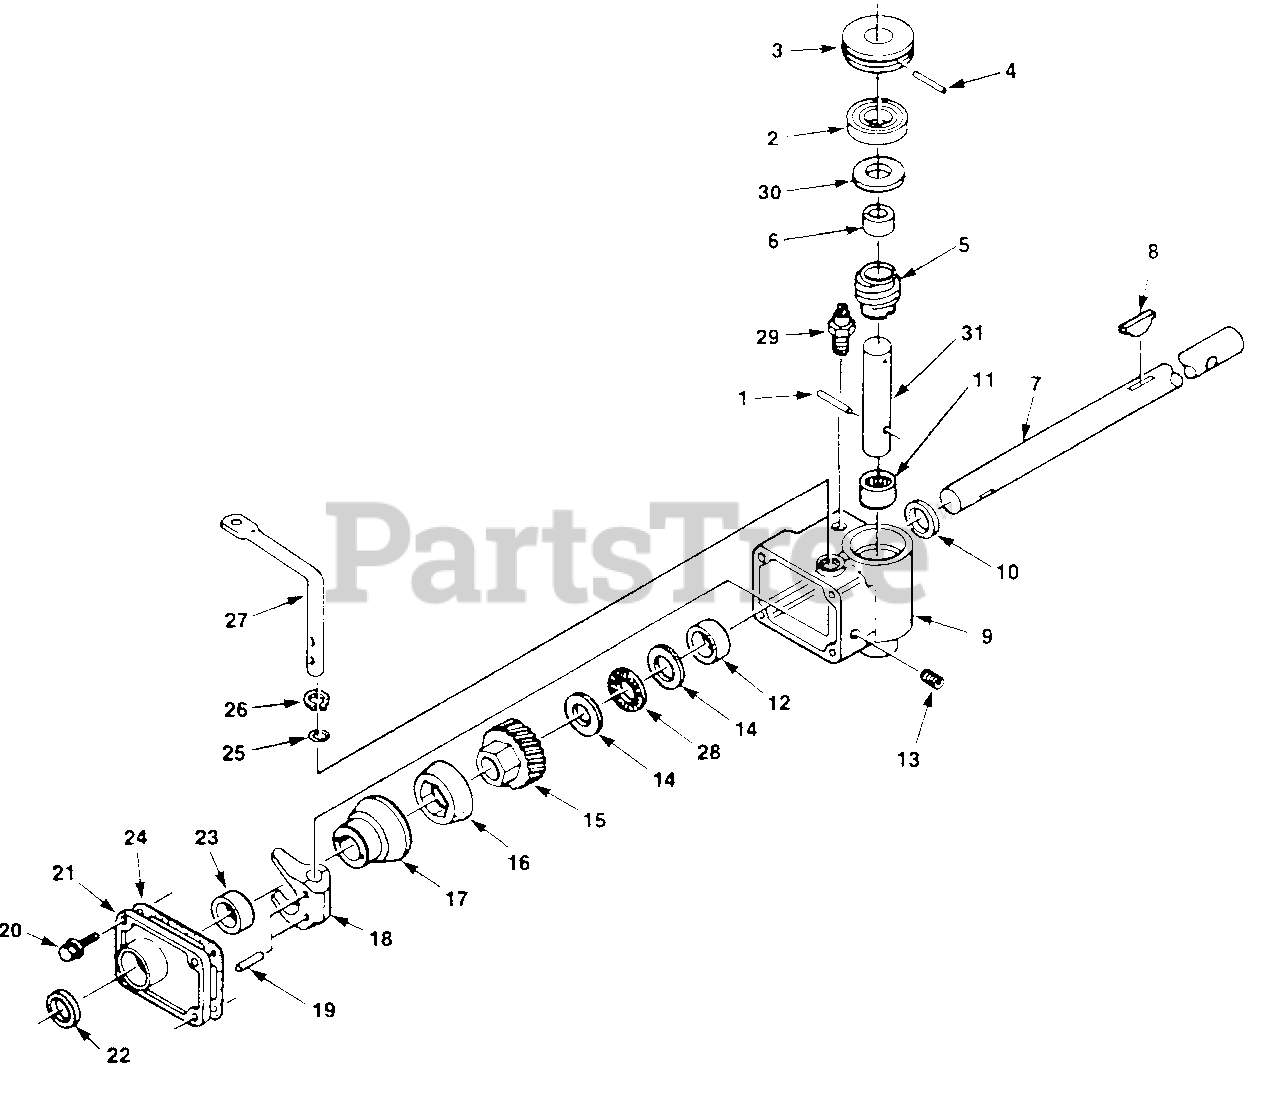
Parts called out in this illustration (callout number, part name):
2	BEARING-Ball
3	PULLEY-Gear box
5	WORM & SPACER
6	SPACER-Worm
7	SHAFT-Drive
9	HOUSING-Gearbox
11	BEARING-Needle
12	BUSHING-Sleeve
13	PLUG-Pipe
14	RACE-Thrust
15	GEAR-Helical
16	CONE-Friction
17	DRUM-Clutch
18	FORK-Shift
19	PIN-Groove
20	SCREW- (1/4-20 x 7/8")
21	GEAR BOX COVER ASSEMBLY
23	BUSHING-Sleeve
24	GASKET-Gearbox
26	TRU-ARC RING
27	LEVER-Shift
28	BEARING-Thrust
31	WORM-Shaft
